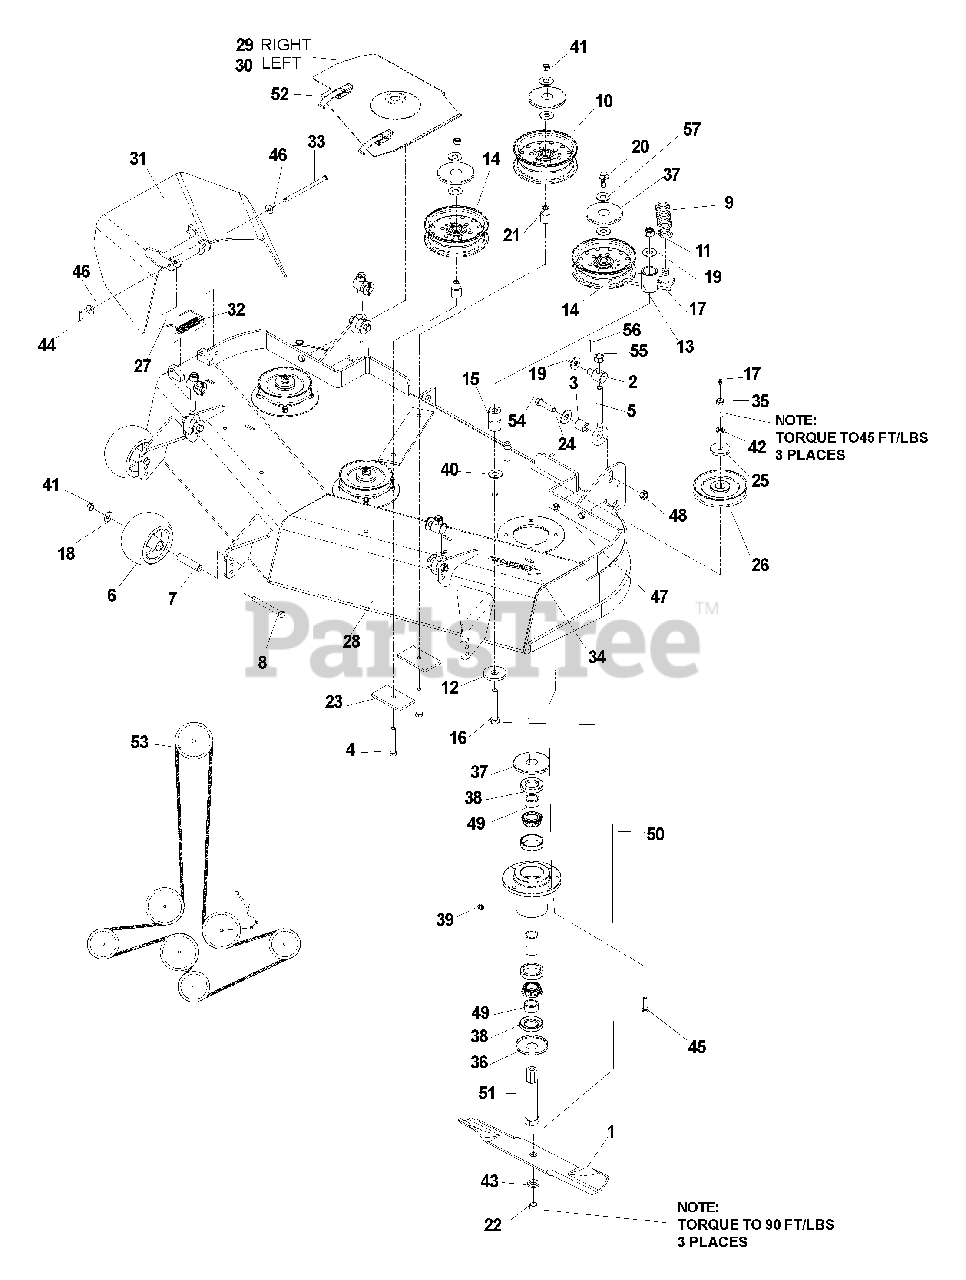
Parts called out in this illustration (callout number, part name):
1	BLADE, 16 1/4
4	HCS, 3/8-16 X 2 3/4, GR5
6	ROLLER, ANTI SCALP
8	HCS, 3/8-16 X 3 1/2, GR8
9	SPRING, EXTENSION
10	PULLEY, IDLER
11	NUT, 1/2-13, NYLOC
12	WASHER, .65
14	PULLEY, IDLER
15	BUSHING, PIVOT
16	HCS, 1/2-13 X 3 1/4, GR5
17	ZERK, STRAIGHT, 1/4-28
18	WASHER, 3/8
19	WASHER, 9/16
20	HCS, 3/8-16 X 1,GR5
21	BUSHING, IDLER
22	HCS, 5/8-18 X 1 1/4, GR5
23	PAD
24	SPRING WASHER, 1/2
25	WASHER, .469
26	PULLEY
27	CAP-SLEEVE
28	DECK W/DECALS
29	BELT SHIELD, RIGHT
30	BELT SHIELD, LEFT
31	DISCHARGE CHUTE
32	SPRING, TORSION
33	PIN-CLEVIS, 5/16 DIA. X 5.19
34	DECAL, TUNNELRAM
35	HCS, 7/16-20 X 1 1/2, GR8, SPEC
36	BOTTOM DUST CAP
37	TOP DUST CAP
38	SHAFT SEAL
39	PLUG, VENTED
40	WASHER, 1/2
41	NUT, 3/8-16, NYLOC
42	LOCKWASHER, 7/16
43	LOCKWASHER, 5/8
44	PIN COTTER, 1/8 X 3/4
45	HCS, 5/16-18 X 1 1/4, GR5
46	WASHER, 5/16
47	NUT, 5/16-18, NYLOC
48	NUT, 7/16-14, CENTERLOCK, GR A
49	TOP & BOTTOM SPACER
50	SPINDLE ASSEMBLY
51	SPINDLE
52	DRAW LATCH
54	HCS, 7/16-14 X 1 3/4, GR5
55	NUT, 1/2-13, NYLOC
56	PIN COTTER, 1/8 X 1
57	WASHER, 3/8, SPEC
